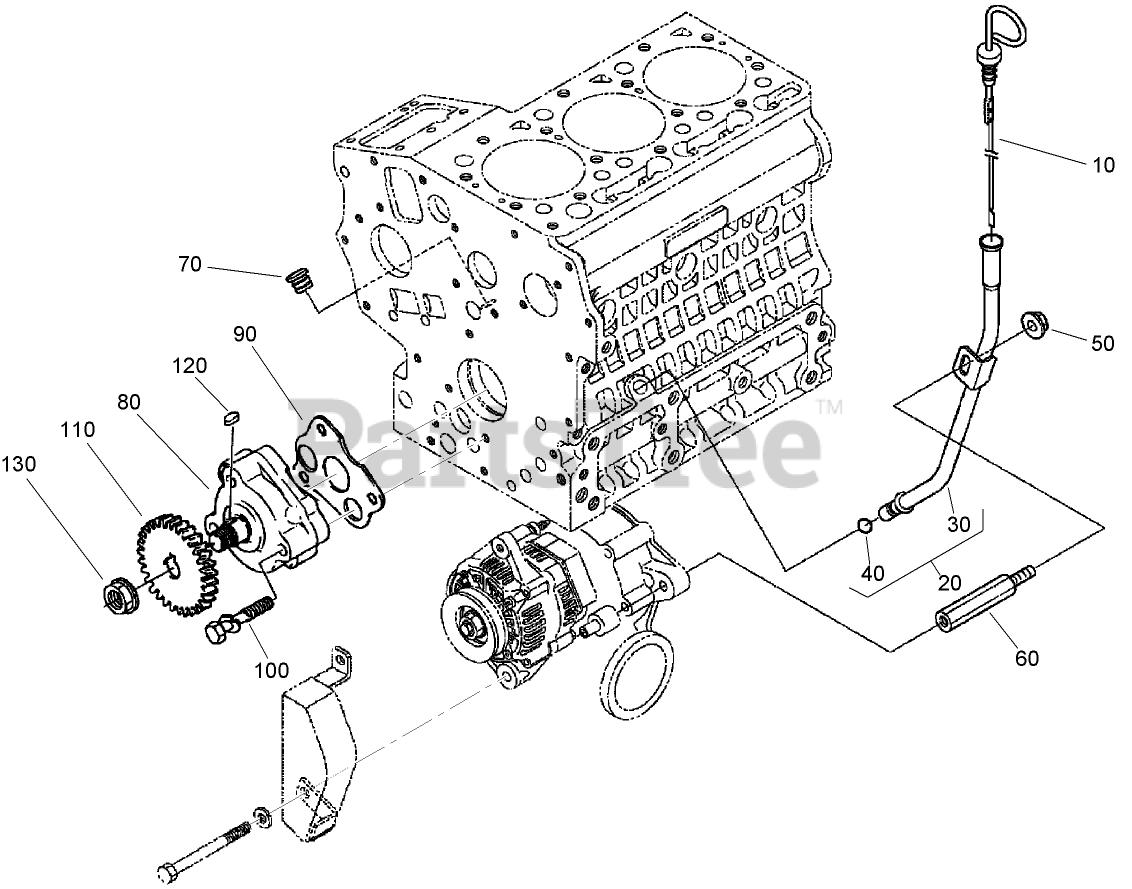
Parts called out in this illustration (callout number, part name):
10	GAUGE-OIL
20	OIL GAUGE GUIDE ASM
30	GUIDE-GAUGE, OIL
40	OBS O-RING
50	NUT-FLANGE
60	SUPPORT-GUIDE, GAUGE
70	PLUG-GAUGE, OIL
80	OIL PUMP ASM
90	GASKET-PUMP, OIL
110	GEAR-DRIVE, OIL PUMP
120	KEY-FEATHER
130	NUT-FLANGE
